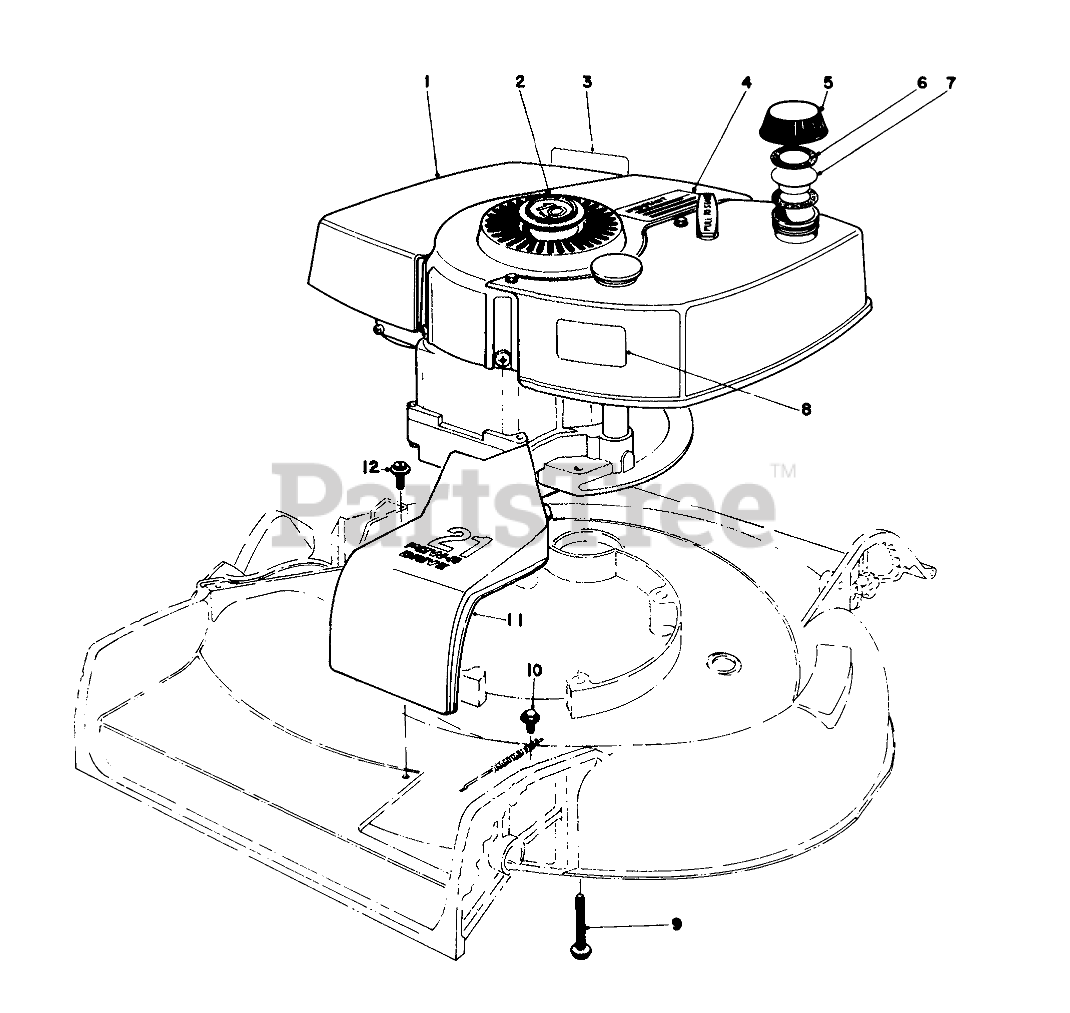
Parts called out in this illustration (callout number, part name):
1	Engine
2	PLUG BUTTON
3	Decal Maintenance
4	Decal Lockout
5	Gas Cap (Incl. Ref. #6 & 7)
6	GASKET
7	GAS CAP BAFFLE
8	Decal Engine
9	3/8-16 X 2-3/4 CAPSCR
10	SCREW-HWHTF
11	BELT DRIVE COVER
12	SCREW
